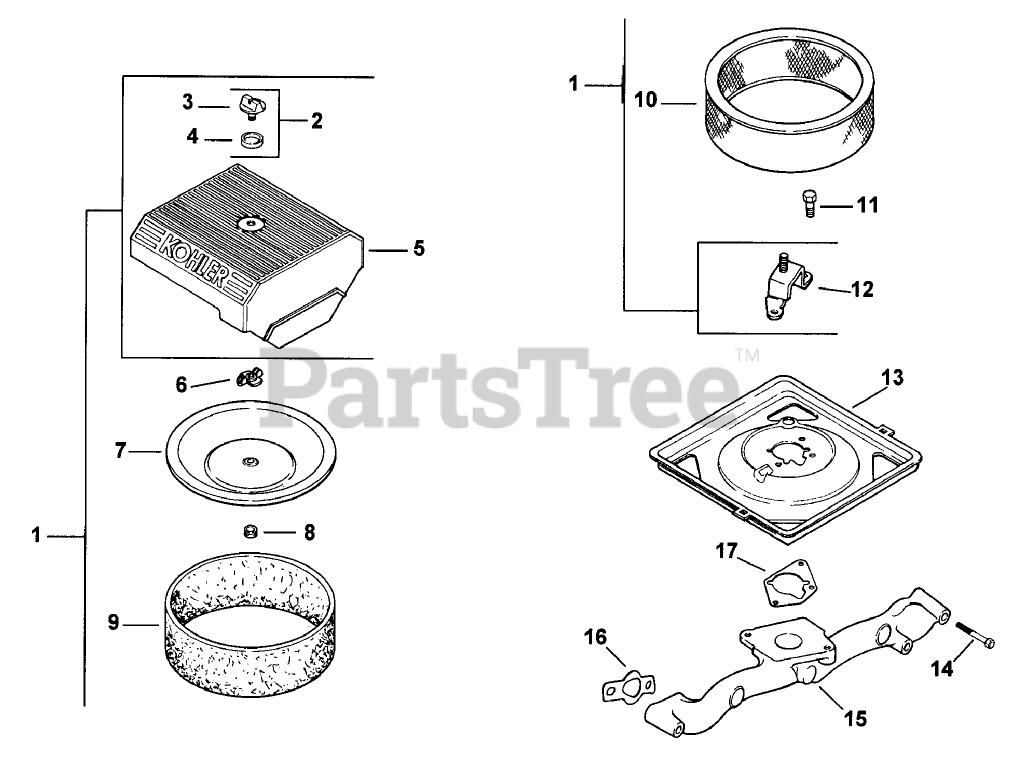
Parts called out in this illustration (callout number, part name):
1	Kit, air cleaner cover (Incl. 2-5, 12)
2	Kit, knob with seal (Incl. 3-4)
3	Knob-Cover
4	O-Ring
5	Cover-Air Cleaner
6	Wingnut
7	Cover-Inner AirCleaner
8	Seal, insert
9	Bement-Precleaner
10	Bement-Air Cleaner
11	Screw
12	Bracket-Air Cleaner
13	Base-Air Cleaner
14	Screw
15	Manifold
16	Gasket-Intake, Manifold
17	Gasket
